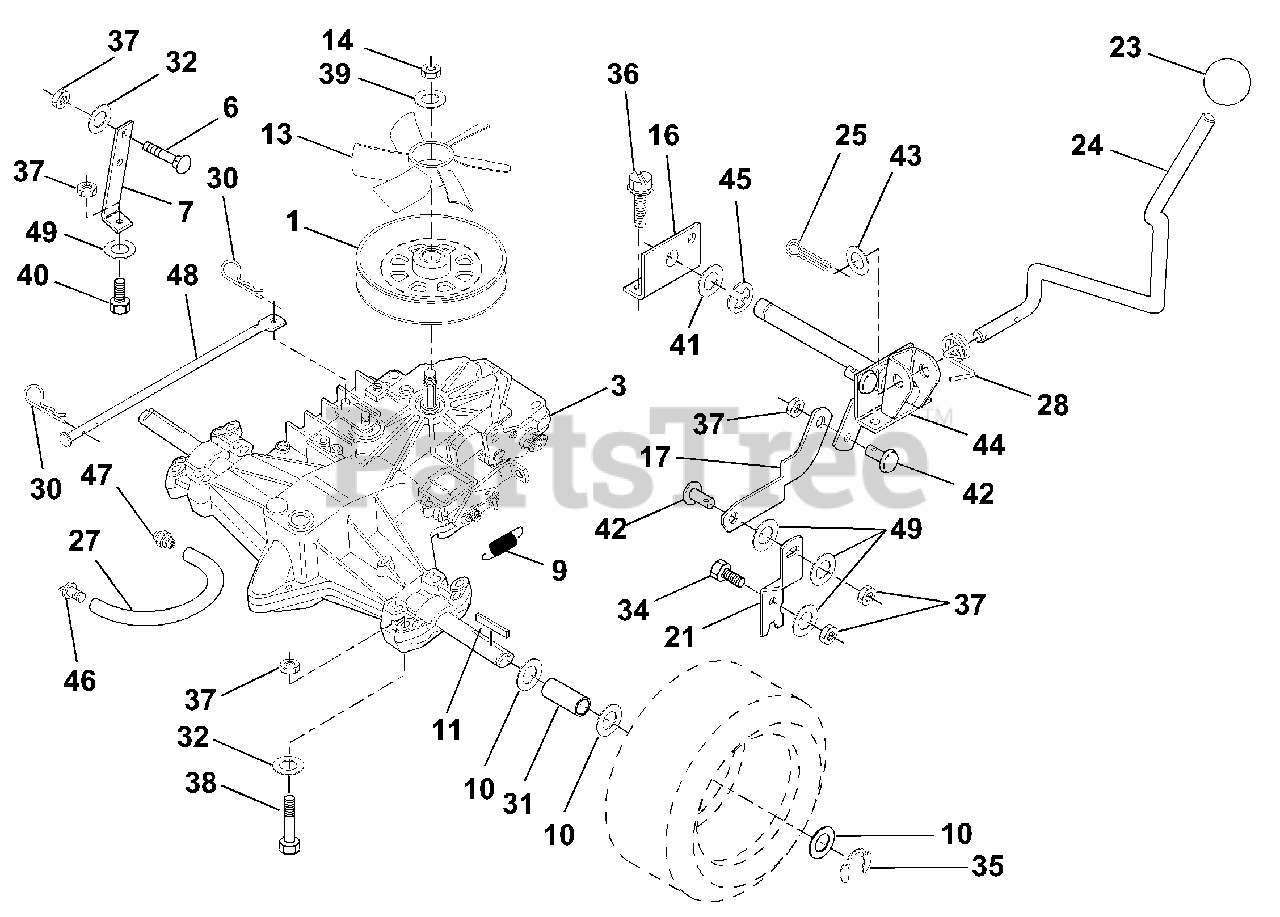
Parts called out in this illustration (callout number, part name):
3	Transaxle, Hydro 0310-0500
6	Bolt, Carriage
7	Strap, Torque
9	Spring Brake
10	Washer 25/32 x 1-1/4 x 16 Gauge
11	Key, Square
13	Fan, Transaxle, Hydro
14	Nut Lock 1/2-20 UNF x 3/4 x 7/16
16	Support, Shift Handle
17	Link, Shift
21	Lever, Shift
23	Knob, Shifter
24	Rod, Shifter
25	Pin, Cotter 1/8 x 1
27	Hose, Vent
28	Spring, Torsion
30	Retainer Spring
32	Washer 11/32 x 11/16 x 16 Ga.
34	Bolt Hex Hd. 5/16-18 x 1
36	Screw, Thd. Cut. 1/4-20 X 1/2
37	Nut Lock Hex w/Ins. 5/16-18
38	Bolt, Hex Flghd. 5/16-18 x 2-1/2
39	Washer 17/32 x 1-3/16 x 12 Ga.
40	Bolt Fin Hex 5/16-18 x 1-1/2
41	Washer 21/32 x 1-1/4 x 13 Ga.
43	Washer 17/32 x 3/4 x 16 Ga.
44	Pivot Shaft Assembly
46	Cap, Vent Hose
47	Nipple, Vent Hose
48	Actuator, Bypass, Hydro
49	Washer 11/32 x 3/4 16 Ga.
